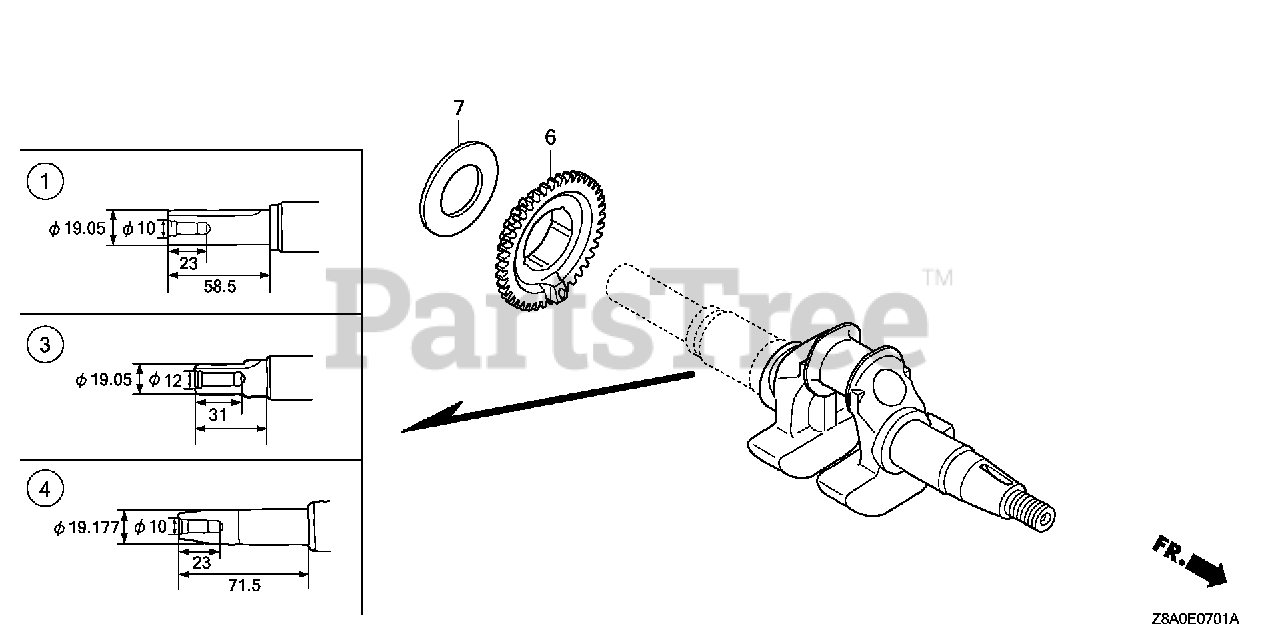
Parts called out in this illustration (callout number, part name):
1	CRANKSHAFT
6	PULLEY, TIMING BELT DRIVE
7	WASHER, THRUST
